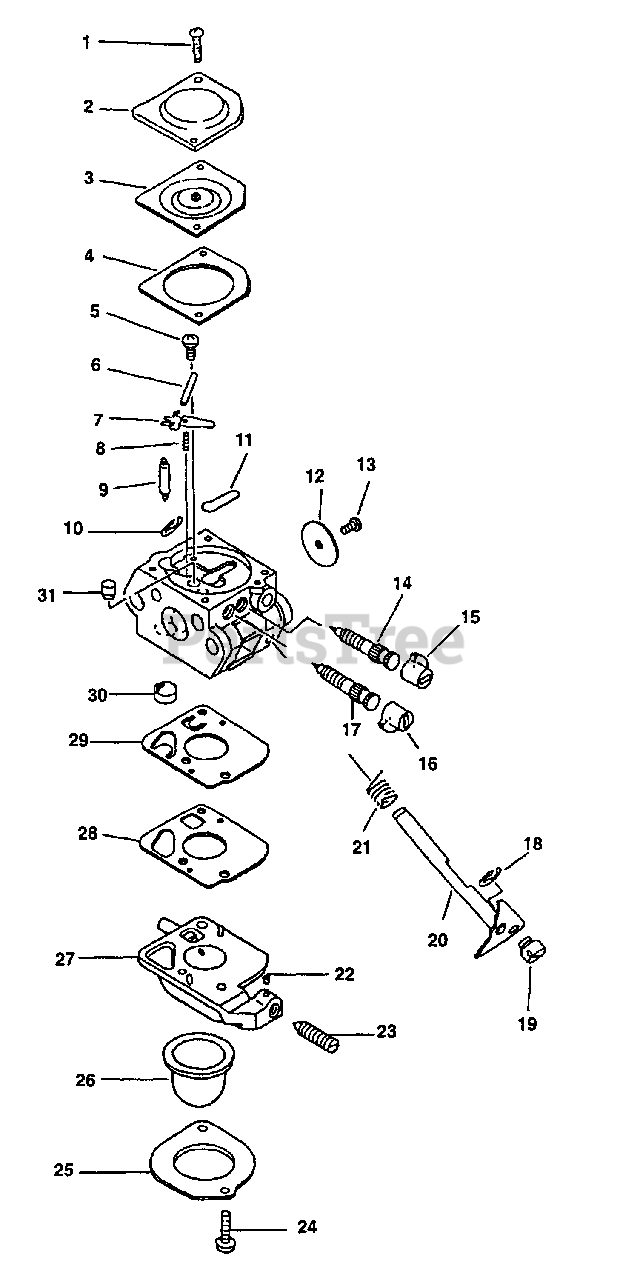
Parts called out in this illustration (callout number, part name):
2	COVER, METERING
3	DIAPHRAGM, METERING
4	GASKET, METERING
5	SCREW, METERING LEVER PIN
6	PIN, METERING LEVER
7	LEVER, METERING
8	SPRING, METERING LEVER
9	VALVE, INLET NEEDLE
10	RING, RETAINING
11	PLUG, WELCH
12	VALVE, THROTTLE
14	NEEDLE - LOW SPEED
15	CAP, LIMITER
16	CAP, LIMITER
17	NEEDLE - HIGH SPEED
18	RING, RETAINING
20	SHAFT, THROTTLE
21	SPRING, RETURN
22	PIECE, FRICTION
23	SCREW, IDLE ADJUST
24	SCREW, RETAINER
25	RETAINER, PURGE BULB
26	BULB, PURGE
27	BASE, PURGE
28	GASKET, PUMP
29	DIAPHRAGM, PUMP
30	STRAINER
31	NOZZLE, CHECK VALVE
